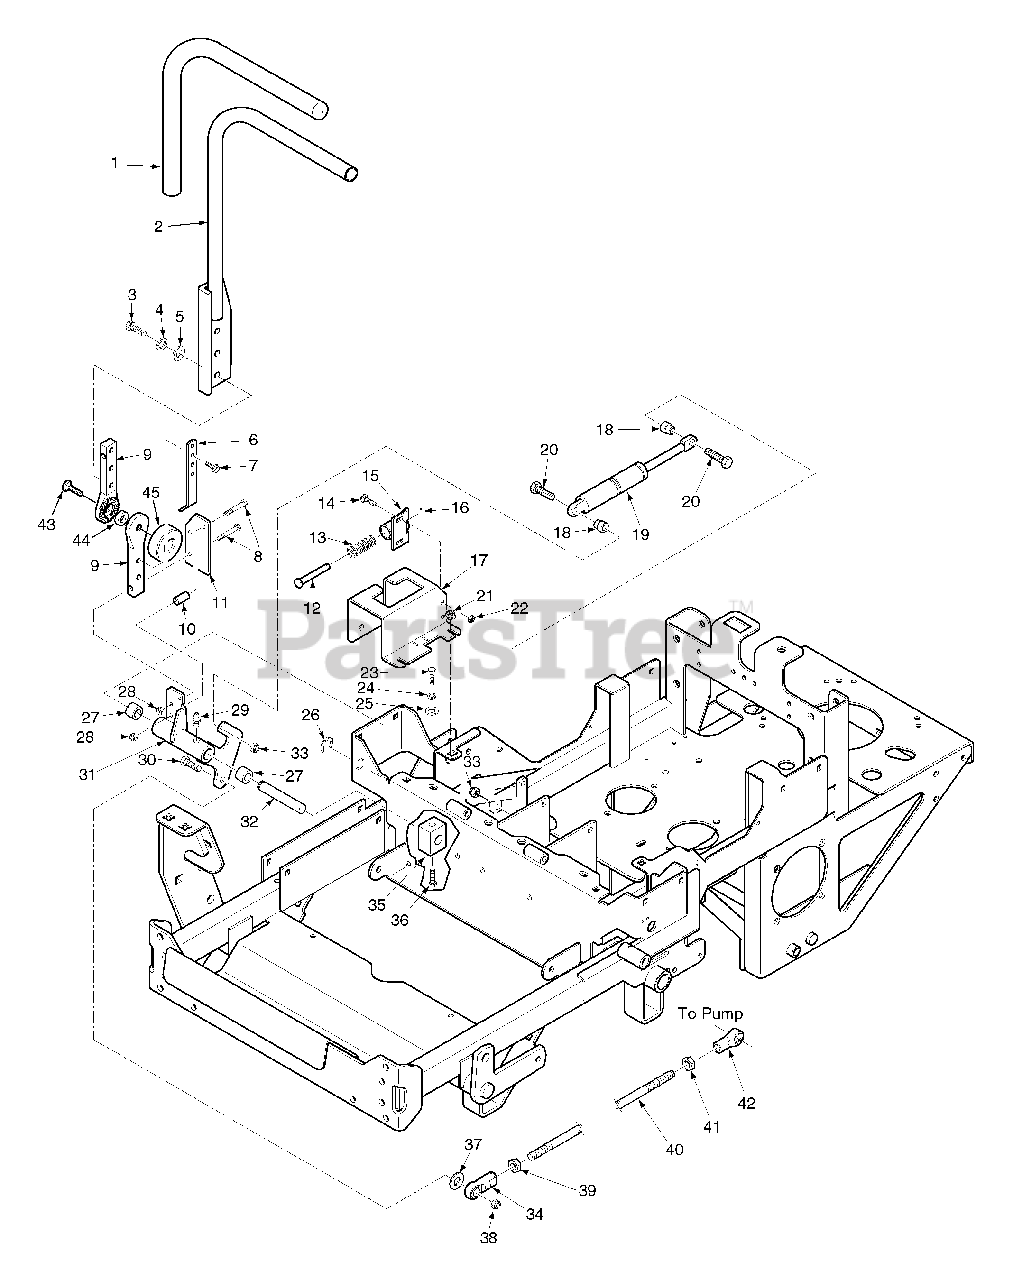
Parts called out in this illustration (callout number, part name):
1	Grip, Handle Bar
2	Handle Bar, LH
3	Bolt, Hex Head 3/8-16 x 1-1/4"
4	Lock Washer, 3/8"
5	Flatwasher, 3/8-.391 x .938 x .105
6	Bracket, Switch Actuator
7	Bolt, Hex Serr. Flange 5/16-18 x 3/4"
8	Bolt, Hex Head 5/16-18 x 2"
9	Control Lever
10	Spacer, Control
11	Plate, Control Lever
12	Pin Retainer
13	Spring
14	Bolt, Carr. 1/4-20 x 3/4"
15	Bracket, Control Return
16	Roll Pin, Spring 5/32 x 3/4"
17	Control Bracket with Decal, L.H.
18	Spacer, Pump Dampener
19	Gas Damper
20	Bolt, Hex Head 5/16-18 x 1-3/4"
21	Nut, Serr., Flange, 5/16-18
22	Nut, Elastic Stop 1/4-20
23	Bolt, Hex Head 3/8-16 x 3/4"
24	Lock Washer, 3/8"
25	Flatwasher, 3/8-.391 x .938 x .105
26	Retaining Ring, 3/4" Ext.
27	Bushing, .753 ID
28	Nut, Elastic Stop 5/16-18
29	Grease Fitting, 1/4-28 Self Tap
30	Bolt, Hex Head 3/8-16 x 1-1/2"
31	Linkage Bellcrank Assembly R.H.
32	Shaft, Steering Control
33	Nut, Elastic Stop 5/16-18
34	Rod End, 3/8-24 RH Female
35	Block, Clamping
36	Bolt, Hex Head 3/8-16 x 1"
37	Flatwasher, 3/8-.391 x .938 x .105
38	Nut, Elastic Stop 3/8-16
39	Nut, 3/8-24 RH Thread
40	Link, Pump 3/8-24 x 10.89"
41	Nut, 3/8-24 UNF-2B LH Thread
42	Rod End, 3/8-24 LH Thread
43	Bolt, Carriage 3/8-16 x 1-1/2"
44	Rubber Spacer
